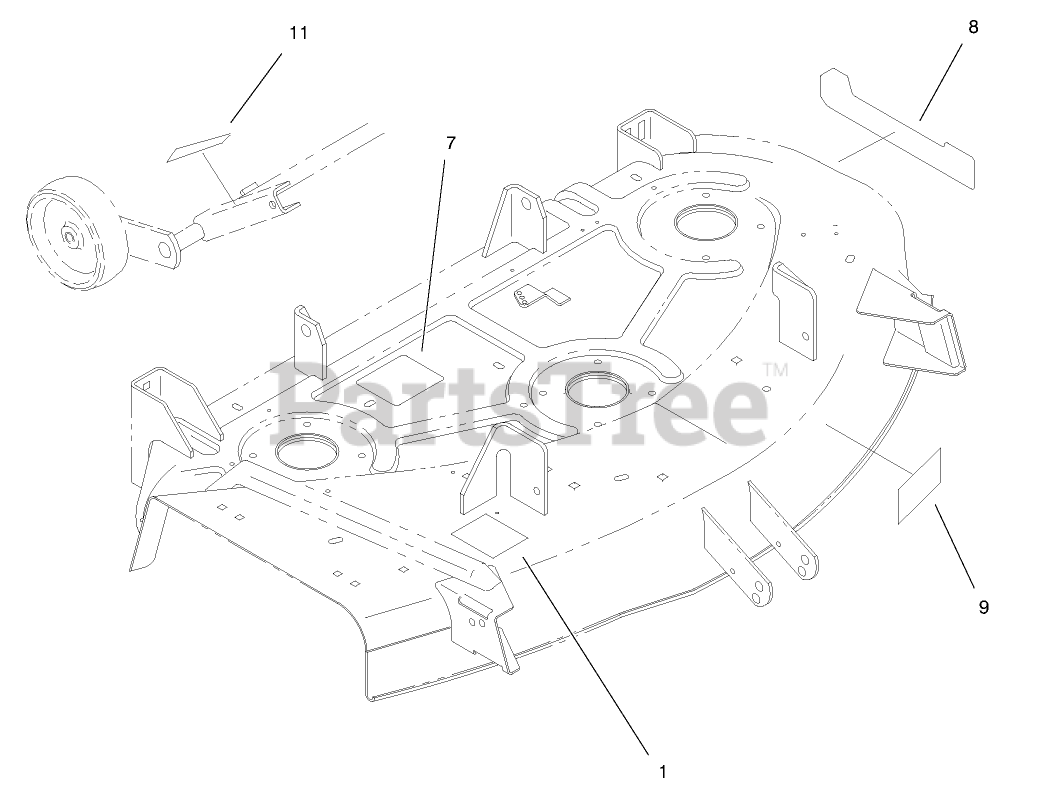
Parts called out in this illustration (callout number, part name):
1	DECAL-BELT ROUTING
7	DECAL-BELT ROUTING
8	DECAL - RECYCLER DECK
9	DECAL-ADJUSTMENT, WHEEL
11	DECAL-HOC
